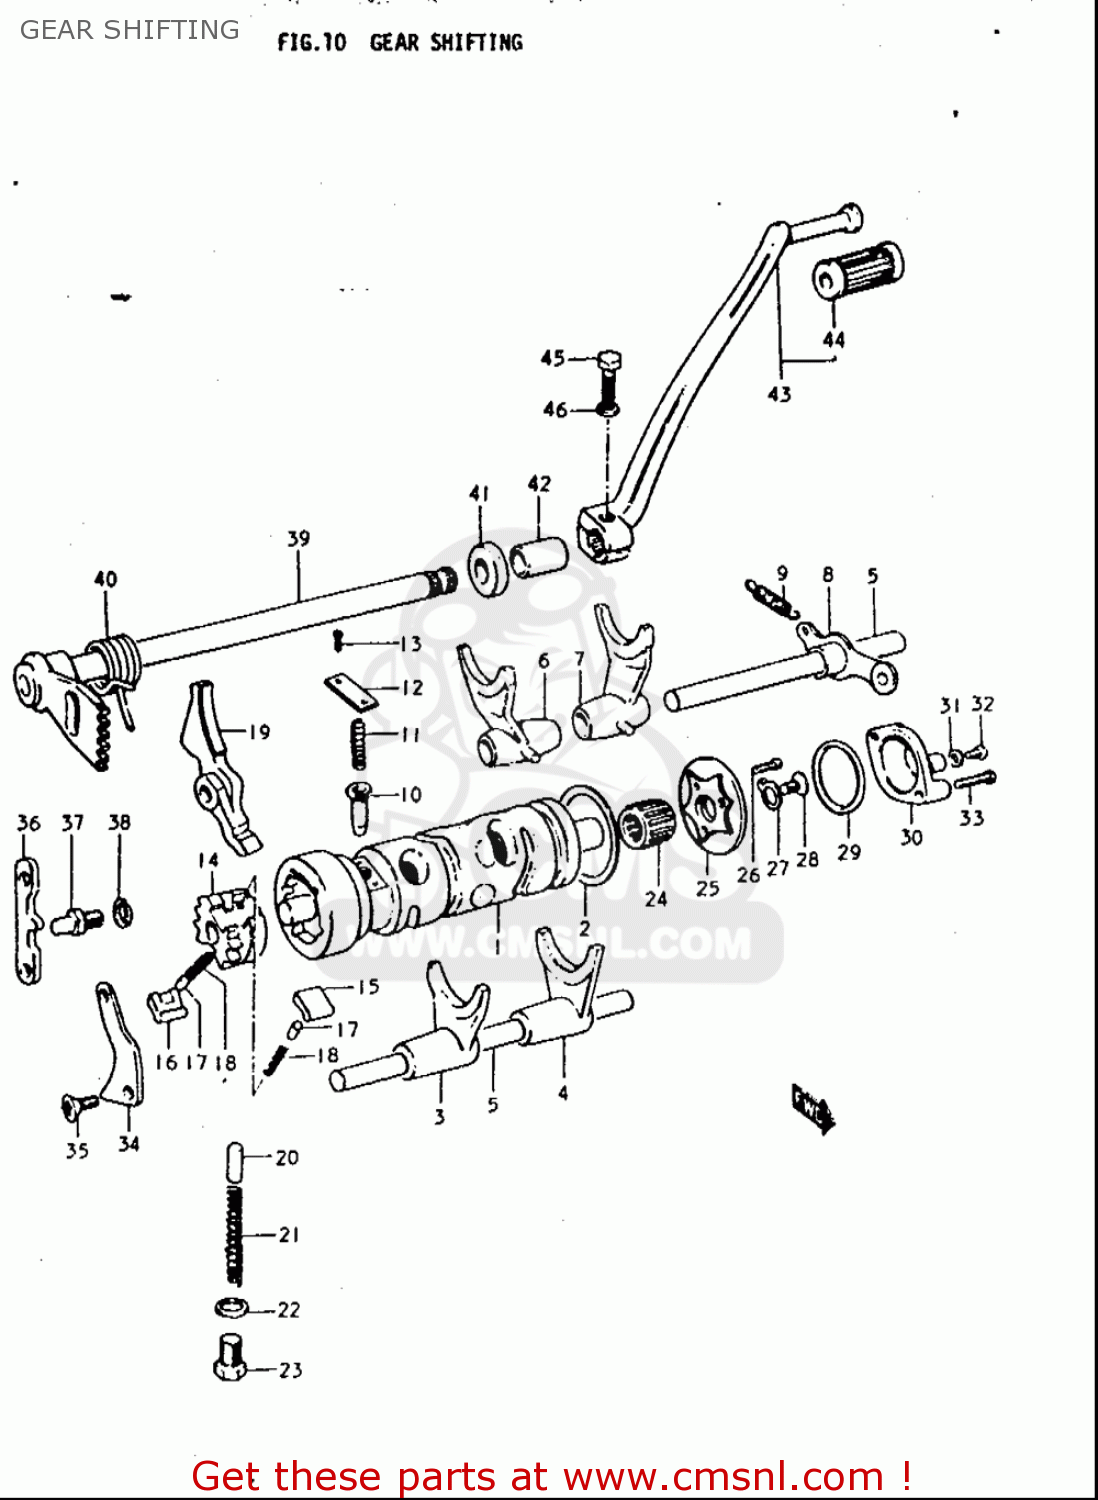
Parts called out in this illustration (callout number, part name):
2	WASHER(40X45X1)
11	SPRING
14	GEAR,GEAR SHIFT CAM DRIVEN
15	PAWL,GEAR SHIFT NO.1
16	PAWL,GEAR SHIFT NO.2
17	PIN(5X8)
18	SPRING
22	GASKET(10X14X3.6) (NAS)
23	PLUG
24	ROLLER BEARING (16X22X1
27	CONTACT,GEAR SHIFT SWITCH
29	O RING(D:1.9,ID:27.7)
30	BODY,GEAR SHIFT SWITCH
31	WASHER
32	SCREW
34	LIFTER,GEAR SHIFT PAWL
36	GUIDE,GEAR SHIFT CAM
37	STOPPER,GEAR SHIFT ARM
38	WASHER,LOCK
40	SPRING
41	SEAL,OIL (12X22X9)
42	CUSHION
43	LEVER ASSEMBLY,GEAR SHIFTING
44	RUBBER,GEAR SHIFT PEDAL
45	BOLT
46	WASHER,LOCK
